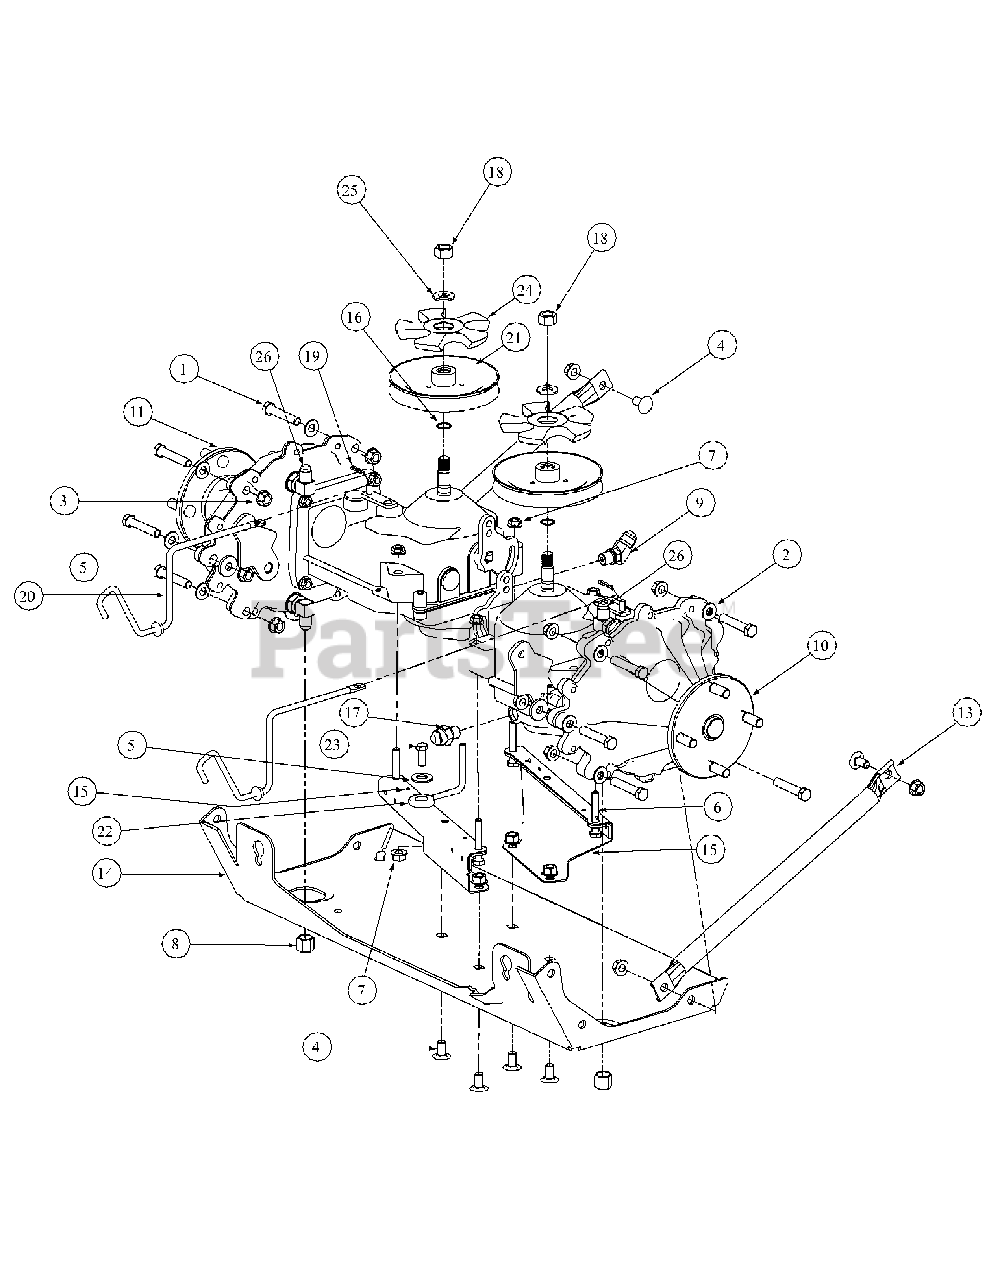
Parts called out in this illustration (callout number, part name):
1	HHCS, 3/8-16, 2.00
2	Flat Washer, 3/8, SAE
3	Hex Nut, 3/8-16, Flange Lock
4	Carriage Bolt, 3/8-16 x .75 Long
5	Flat Washer, .385 x 1.0 OD x .13
6	HHCS, 5/16-18, 2.00
7	Lock Nut, Hex Flange, 5/16-18
8	Nut, Cap, 3/8
9	Elbow Fitting, 3/8-1/2, 45 degree
10	Pump Assembly, Right Hand
11	Pump Assembly, Left Hand
13	Strut, Frame
14	Plate Assembly, Skid
15	Bracket Assembly, Support Pump
16	Ring, Wire
17	Fitting Connector, 1/2 x 3/8
18	Nut, 1/2-20, Hex insert Lock Jam
19	Cotter Pin, .0721 x 1.12 Long
20	Rod, Release, Pump
21	Pulley, Transmission Hydro, Slotted
22	Guide, Traction Drive Belt
23	Hex, Cap Screw, 5/16-18 x 1.0
24	Hydro Pulley Fan
25	1/2" Flat Washer
26	Fitting Elbow, 3/8 x 3/8
